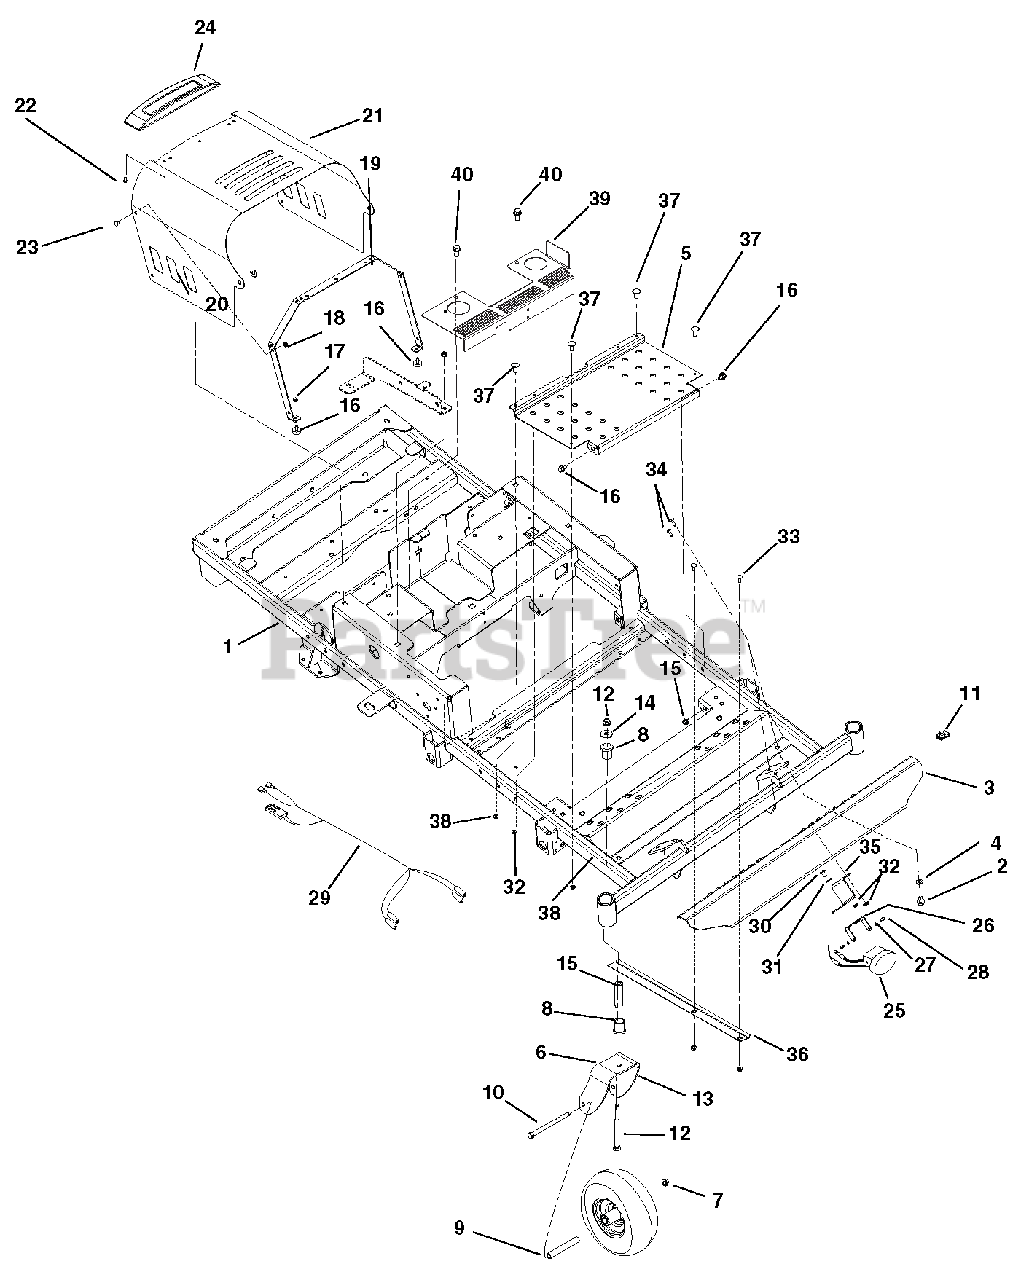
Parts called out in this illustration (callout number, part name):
1	WLDMT, FRAME ZT/ZOOMXL (2013)
2	@BLT-HEX .38-16X1.00 GR5 YWZC
3	WMT, FOOTREST
4	@WSHR-LK .38X.094 REG YWZC
5	PANEL WLDMT, FOOT PLATE
6	WMT, CASTER FORK
7	TIRE/WHEEL ASSY, 11X4-5
8	BSHG-FLG 1.00X1.25X1.50X1.50EP
9	SPACER, ROLLED WHEEL
10	@BLT-HEX .50-13X6.50 GR5 YWZC
11	NUT-RTNR .375-16X.37
12	@NUT-LK-TOP-FLG .50-13 YWZC
13	@BLT-HEX .50-13X5.00 GR5 YWZC
14	WSHR-FL-STL.511X1.441X.125 YWZ
15	SPACER, CASTER FORK
16	BUMPER, RUBBER
17	@NUT-LK-TOP-FLG .31-18 YWZC
18	@NUT-LK-TOP-FLG .25-20 YWZC
19	HOOD STRAP
20	WSHR-FL-NYL .518X1.000X.080
21	HOOD-ZTXL
22	SCR-.25X.62 PN HD BOSSSCREW YZ
23	@BLT-RDHDSQNK .25-20X.50 G5YZ
24	TRIM-ZOOM XL HOOD ARIENS
25	KIT, ZOOM/ZT XL LIGHT
26	WMT, LIGHT BRACKET
27	WSHR-LK 4MMX1MM REG CL ZINC
28	SCREW-M4X.07X8 SHCS CLZNC
29	HARNESS,MINI-Z HEADLIGHT
30	SCR-CAP BTHD.31-18X.50 GR5 YZ
31	@WSHR-LK .31X.078 REG YWZC
32	@NUT-LK-NYL-FLG .25-20 YWZC
33	@BLT-RDHDSQNK .31-18X.75 G5YZ
34	@BLT-HEX .25-20X.75 GR5 YWZC
35	BRACKET, LIGHT MOUNT
36	BRACKET, LIGHT HARNESS
37	@BLT-HEX .31-18X1.00 GR5 YWZC
38	@NUT-LK-NYL-FLG .31-18 YWZC
39	BRACKET, XL CE FAN GUARD
40	@SCR-TAP .38-16X.50 HWH TR YWZ
